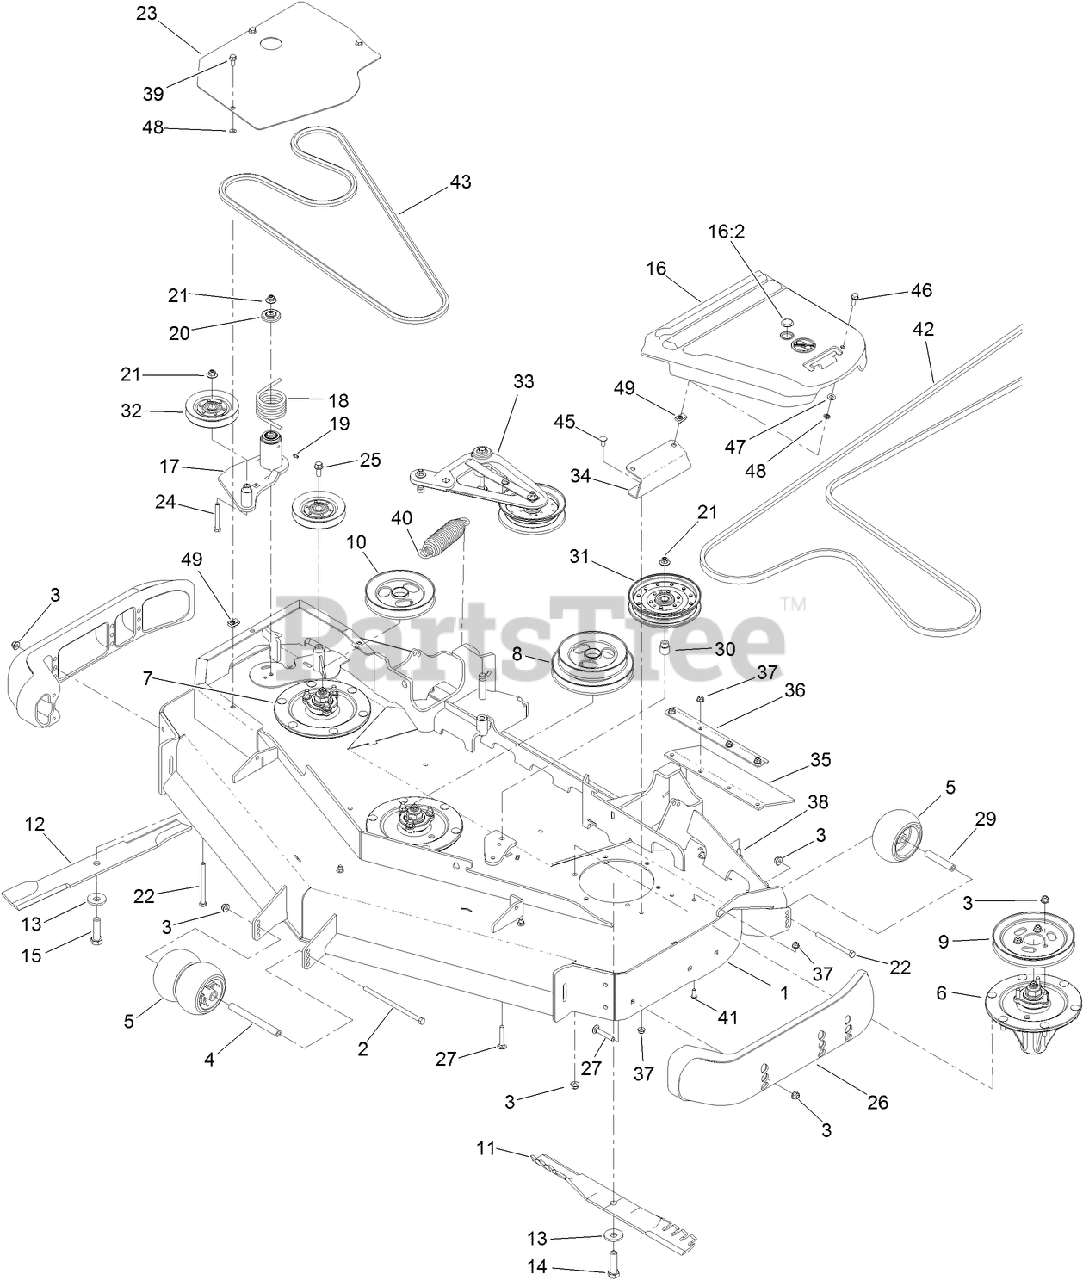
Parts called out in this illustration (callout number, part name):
1	DECK DECAL ASM
2	SCREW-HH
3	NUT-HF, NI
4	SPACER-WHEEL
5	ROLLER-SCALP, ANTI
6	SPINDLE ASM
7	LH SPINDLE ASM
8	PULLEY
9	Pulley
10	PULLEY
11	BLADE-ATOMIC, 20.5IN
12	BLADE-ROTARY, 20.5IN LOW FLOW
13	Washer-Blade Bolt, Heavy
14	SCREW-BLADE
15	SCREW-BLADE, LH
16	LH BELT COVER ASM
16:2	PLUG-PLASTIC
17	DECK IDLER ASM
18	SPRING-TORSION
19	FITTING-GREASE
20	GUARD-TOP
21	NUT-FLANGE, NI
22	SCREW-HH
23	PLATE-BELT COVER, RH
24	SCREW-HH
25	SCREW-HHF
26	SKID-BUMPER, DECK
27	SCREW-CARR
29	TUBE-SPANNER
30	Bushing, Idler
31	PULLEY-IDLER, FLAT
32	SHEAVE
33	DECK IDLER ASM
34	BRACKET-COVER, BELT
35	GUARD-TIRE
36	SUPPORT-OUTER FLAP
37	NUT-HF, NI
38	SCREW-CARR
39	SCREW-HHF
40	SPRING-EXTENSION
41	SCREW-HSBH
45	SCREW-CARR
46	SCREW-HHF
47	WASHER-THRUST
48	NUT-PUSH
49	NUT-U
